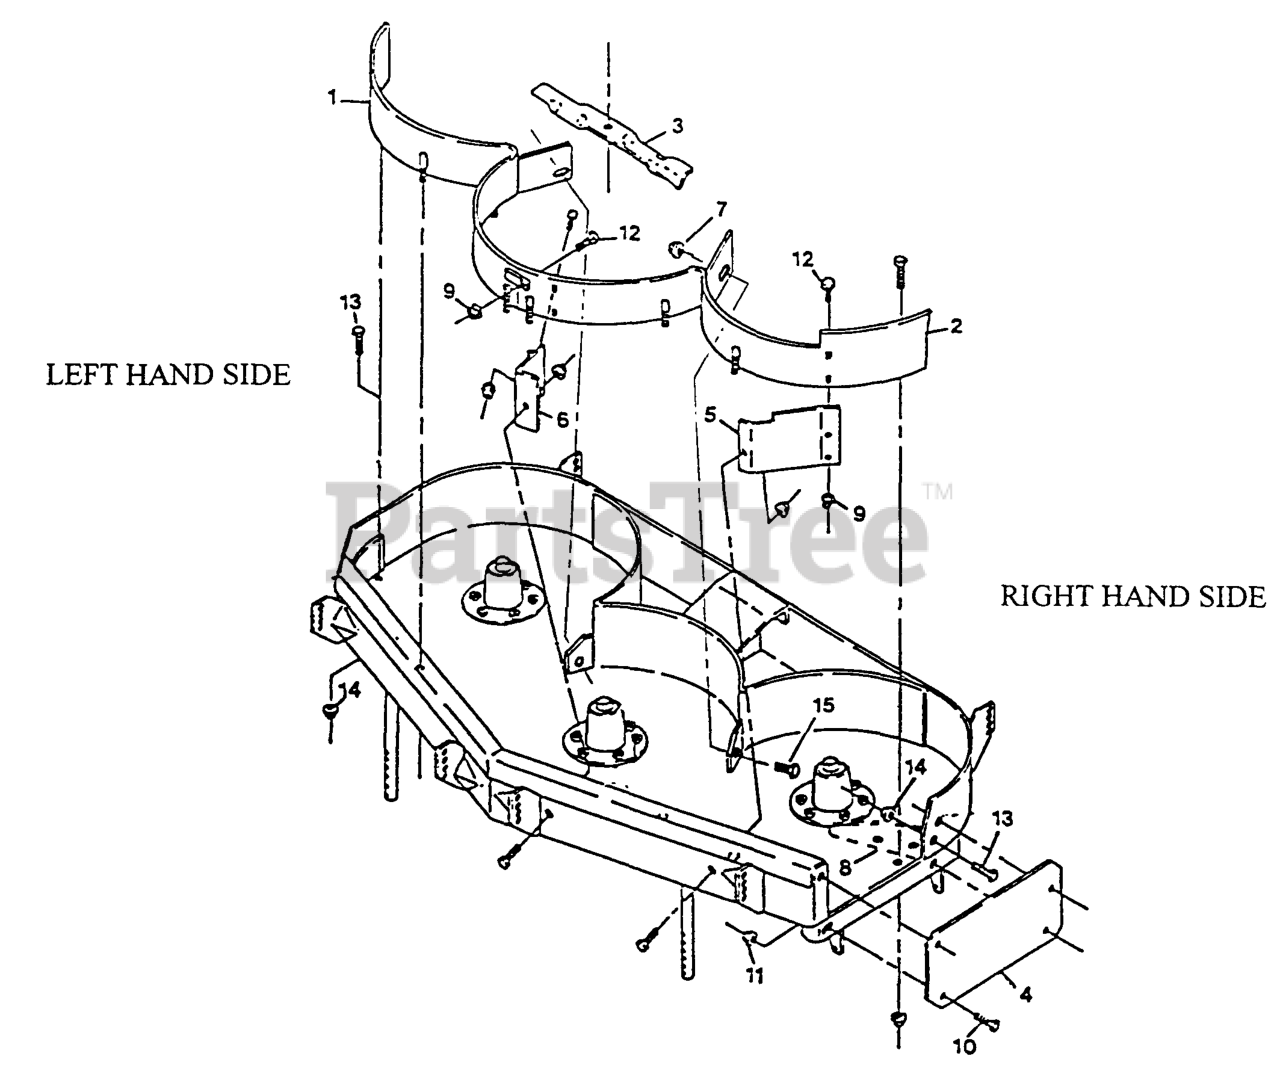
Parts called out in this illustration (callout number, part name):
1	WLD,BAFFLE LH 60
2	WLD,BAFFLE RH 60
4	PLATE-COVER
8	WLD,BAFFLE DISCHARGE
12	BOLT-CARR
